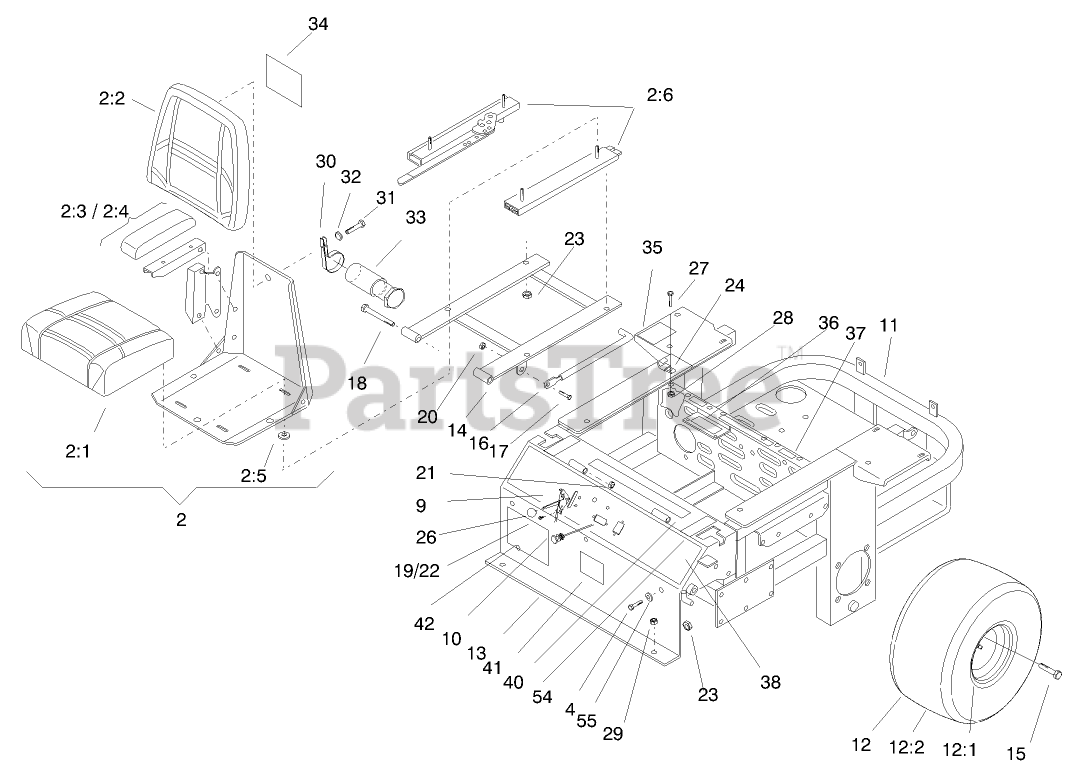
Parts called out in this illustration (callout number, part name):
2	Seat ASM
2:1	Cushion
2:2	Cushion
2:3	Armrest
2:4	Armrest
2:5	Spacer-Track
2:6	Track-Locking, 4"
4	SCREW-HH
9	Cable
10	Cable-Choke
11	Frame
12	Wheel & Tire ASM
12:1	Wheel
12:2	Tire
13	Console w/Decal
14	Frame-Seat
15	Wheel Bolt
16	Rod-Seat Holdup
17	SCREW-HH
18	SCREW-HH
19	Nut
20	Nut-Lock
21	NUT-HEX
22	Bolt-CARR
23	NUT-HF
24	Clip
25	Tie-Plastic
26	Knob
27	SCREW-HH
28	NUT-HF
29	Bumper
30	CLAMP-R
31	SCREW-HWHTF
32	WASHER-FLAT
33	TUBE-MANUAL
34	DECAL
35	Decal-Belt Pump
36	Decal-Drive Release
38	Decal-Control Panel
40	Decal-Battery
41	Decal-Fuel Valve
42	Decal-Z252
54	Decal-Motion Control
55	WASHER-PLAIN
